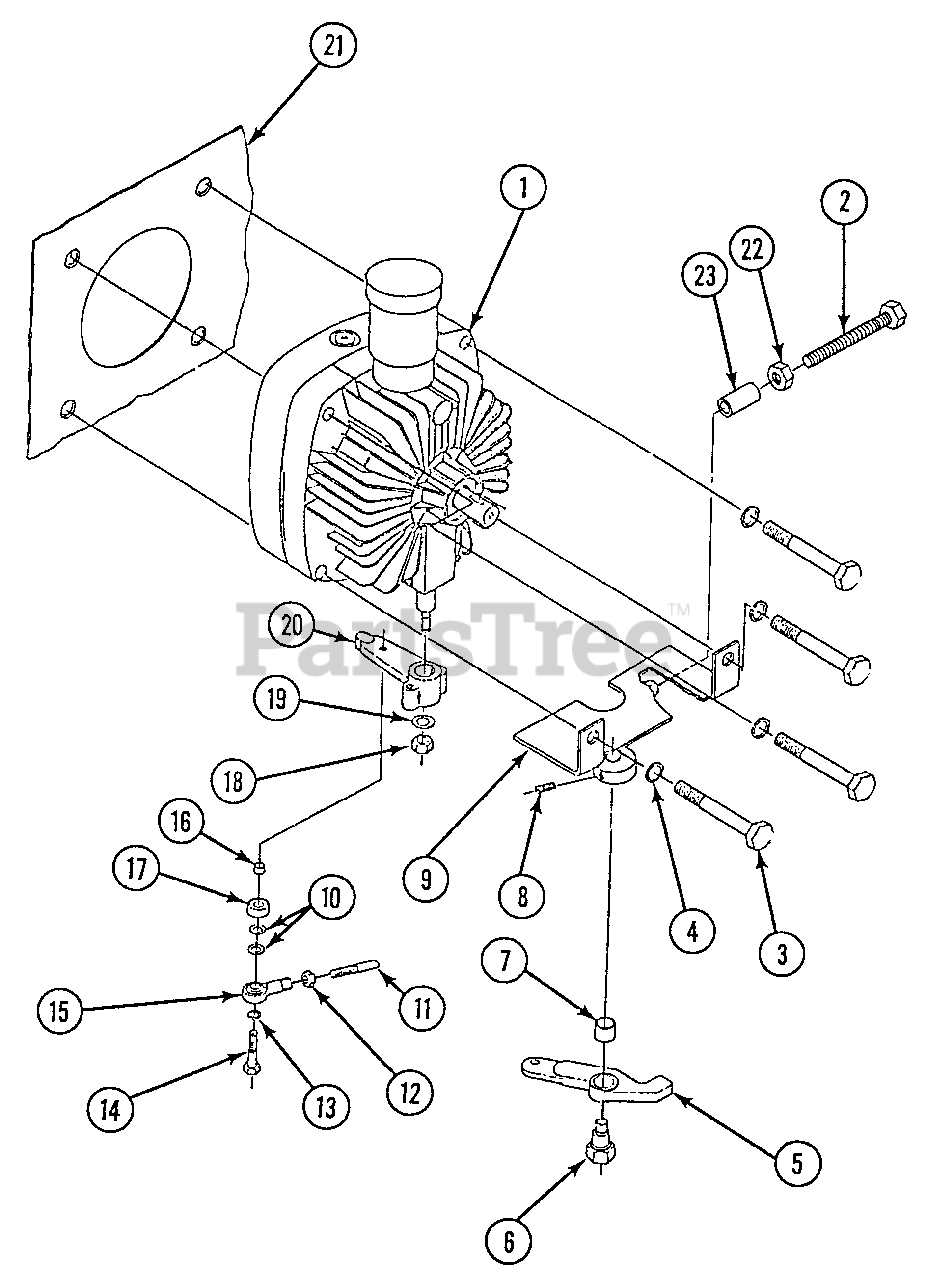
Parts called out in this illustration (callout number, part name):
1	HYDRO, LEFT
1	HYDRO, RIGHT
2	CAPSCREW, 5/16-16 X 3 FULL THRD. GR.2
3	CAPSCREW, 3/8-16 X 3 GR. 5
4	LOCKWASHER, 3/8 SPLIT SPRING
5	CAM BAR
6	CENTERING CAM
7	BUSHING, BRONZE
8	SCREW, HX. SCKT 1/2 DOG SET
9	CENTERING CAM BRKT. WLDT. LEFT
9	CENTERING CAM BRKT. WLDT. RIGHT
10	WASHER, 6.4 MM I.D. (ZINC PLATED)
11	PUSH-PULL CABLE, LEFT
11	PUSH-PULL CABLE, RIGHT
12	NUT, 1/4-28 (COMES WITH #11)
13	LOCKWASHER, 1/4 SPLIT SPRING
14	CAPSCREW, 1/4-20 X 1-1/2 GR.5
15	BALL JOINT, FEMALE 1/4-28
16	BUSHING BALL JOINT
17	BEARING, CAM
18	NUT, 3/8-16
19	WASHER, 3/8 STD. FLAT
20	CONTROL ARM
21	SIDE PLATE WLDT. LEFT
21	SIDE PLATE WLDT. RIGHT
22	NUT, 5/16-18 PLAIN
23	SPACER, STOP
